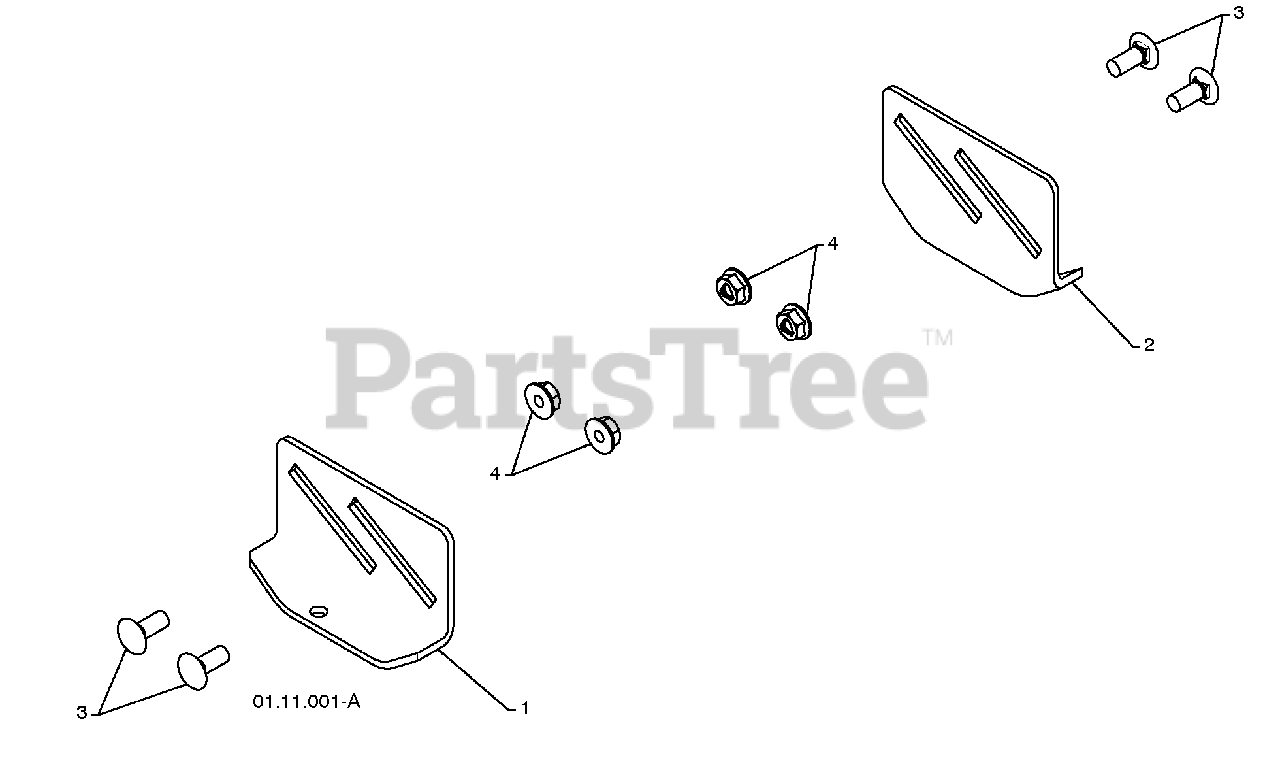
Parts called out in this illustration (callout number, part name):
1	SKID PLATE LH
2	SKID PLATE RH
3	CARRIAGE BOLT 5/16-18 X .75
4	NUT 5/16-18
